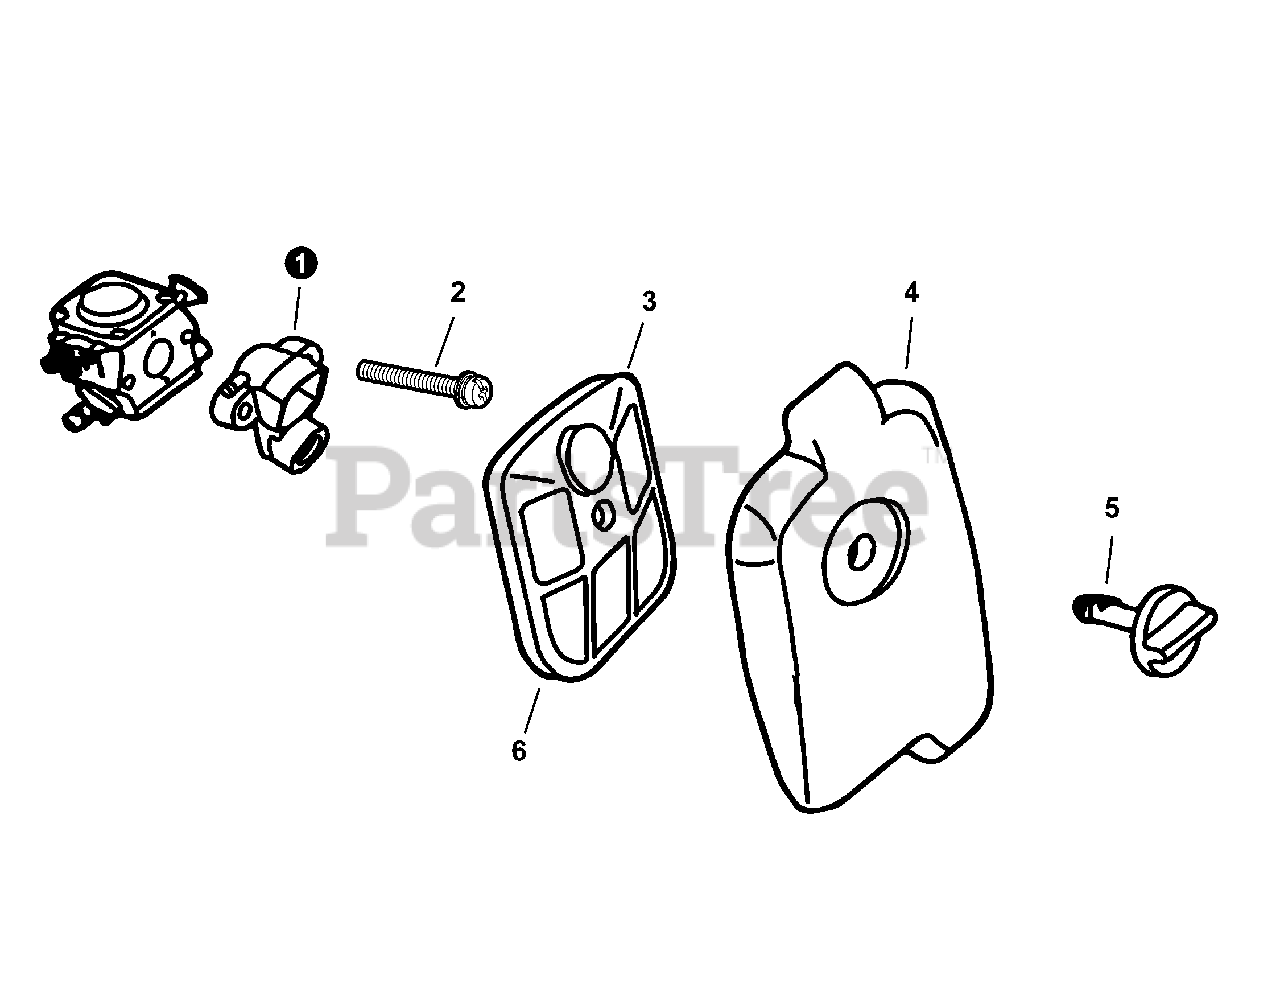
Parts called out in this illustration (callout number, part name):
1	ADAPTOR, AIR FILTER
2	SCREW 5×50
3	FILTER, AIR
4	COVER, AIR FILTER
5	THUMBSCREW
6	TUNE-UP KIT - REPOWER
